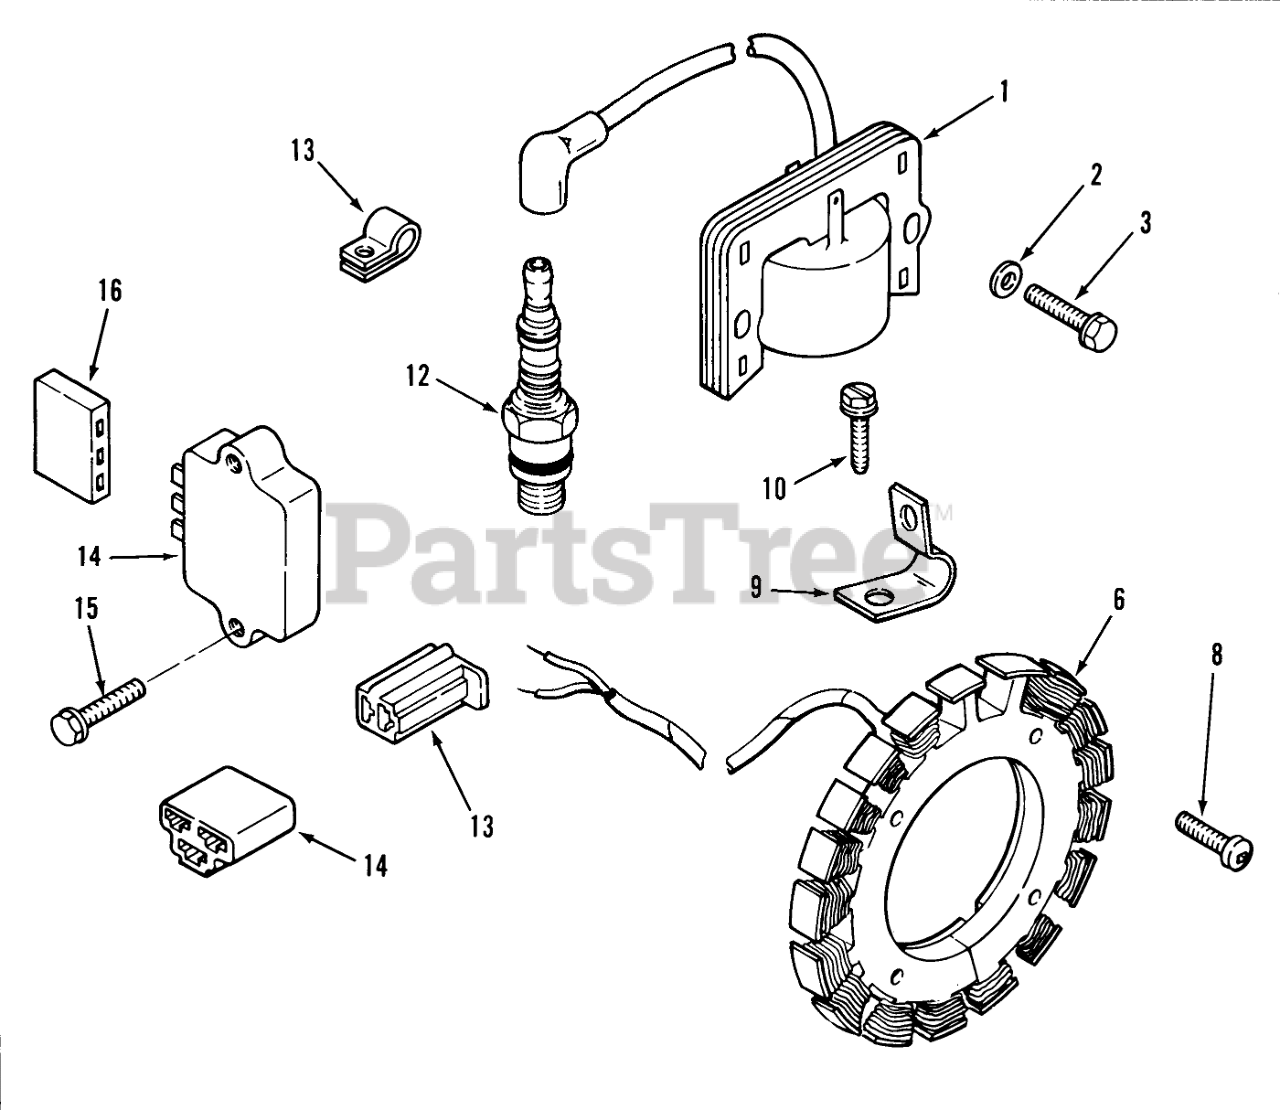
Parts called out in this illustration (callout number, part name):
1	Ignition Module (Before Serial #1715900013)
1	Module-Ignition
2	Washer
3	Screw
6	Stator Kit 15amp (Includes Item #8)
8	Pozidriv. Pan Hd. Screw #10-24 x 3/4
10	Screw-Hex. Hd.
12	Plug-Spark
13	Clip-Hi-Tension
14	Regulator-Rectifier
15	Screw
16	Connector
